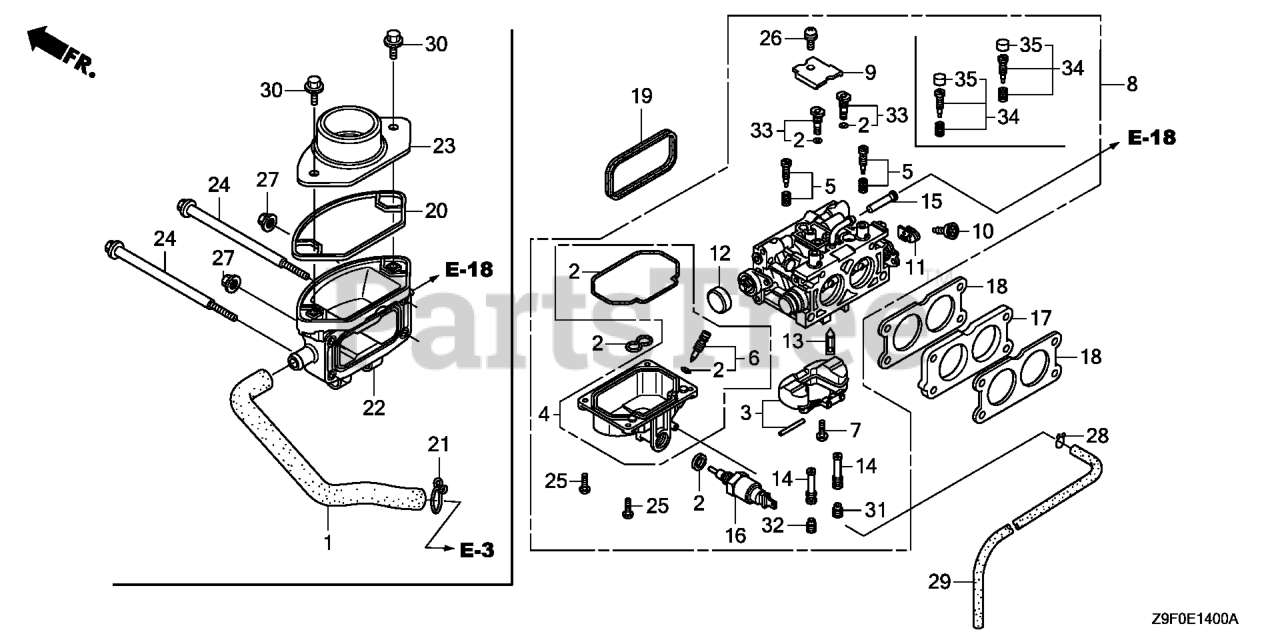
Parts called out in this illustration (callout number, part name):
1	TUBE, BREATHER
2	GASKET SET
4	CHAMBER SET, FLOAT
5	SCREW SET (CARBURETOR NO.)
6	SCREW SET, DRAIN (ADVENTURE GREEN) (CARBURETOR NO.)
7	SCREW, FLOAT
8	CARBURETOR ASSY. (BK07M B)
10	SCREW, THROTTLE STOP
11	ARM, THROTTLE LINKAGE
12	CAP, CHOKE LEVER DUST
13	VALVE, FLOAT
14	NOZZLE, MAIN
15	SCREEN, FUEL STRAINER
16	VALVE ASSY., SOLENOID
17	INSULATOR, CARBURETOR
18	GASKET, CARBURETOR
19	GASKET, AIR CLEANER
20	SEAL, AIR CLEANER HOUSING
21	CLIP, BREATHER TUBE
22	ELBOW, AIR CLEANER
23	JOINT, CONNECTING TUBE
24	BOLT, FLANGE (6X106)
25	SCREW, PAN (4X12)
26	SCREW-WASHER (5X10)
27	NUT, FLANGE (6MM)
28	CLIP, TUBE (B8)
29	BULK HOSE, VACUUM (4.5X1000) (4.5X450) (BULK HOSE 95005-45008-10M)
30	BOLT, FLANGE (6X12) Use up to Engine SN 1543277.
31	JET, MAIN (#92)
31	JET, MAIN (#98) Use from Engine SN BE87A A to BE87A A.
31	JET, MAIN (#105) Use from Engine SN BE87H A.
32	JET, MAIN (#92)
32	JET, MAIN (#98) Use from Engine SN BE87A A to BE87A A.
32	JET, MAIN (#105) Use from Engine SN BE87H A.
33	JET SET, PILOT (#40) (ADVENTURE GREEN) (CARBURETOR NO.)
34	SCREW SET (CARBURETOR NO.)
35	CAP, ADJUSTING SCREW (CARBURETOR NO.)
